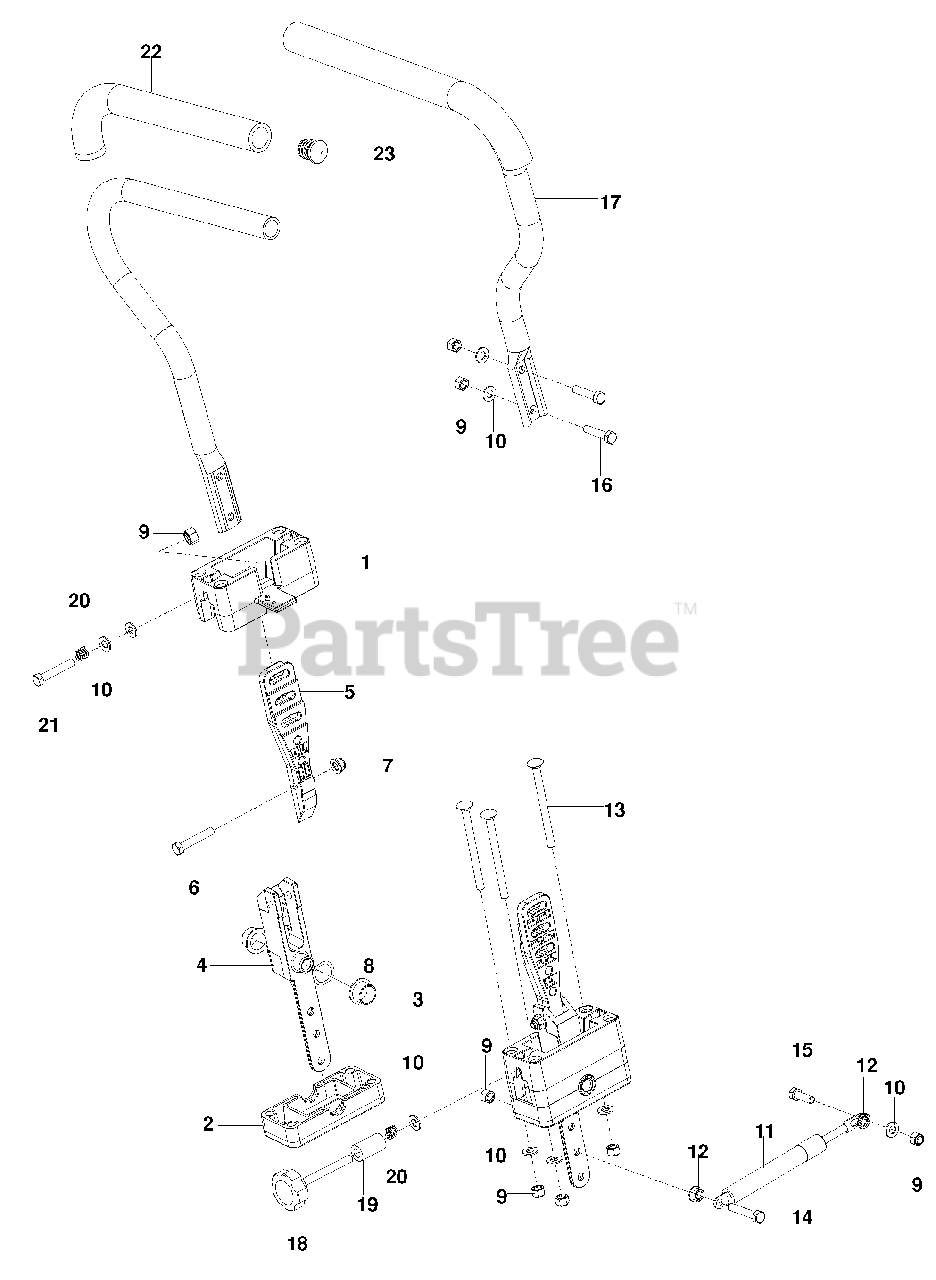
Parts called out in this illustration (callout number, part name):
1	BLOCK, UPPER
2	BLOCK, LOWER
3	BEARING, FLANGE
4	PIVOT SECTION, DRIVE
5	MOUNT, DRIVE CONTROL
6	HCS 5/16-18 x 1 3/4 TPBLT
7	NUT 5/16-18 FLANGE NYLOC
8	WASHER, .825 x 1.087 WAVE
9	NUT 5/16-18 HEX NYLOC
10	WASHER 5/16 SAE FLAT
12	NUT 5/16-18 HEX WHIZLK
13	RHSNB 5/16-18 x 4
14	HCS 5/16-18 x 1 3/4 TPBLT
15	HCS 5/16-18 x 1
16	HCS 5/16-18 x 1 1/2
17	LEVER, w/GRIP
21	HCS 5/16-18 x 2 TPBLT
22	GRIP, FOAM
